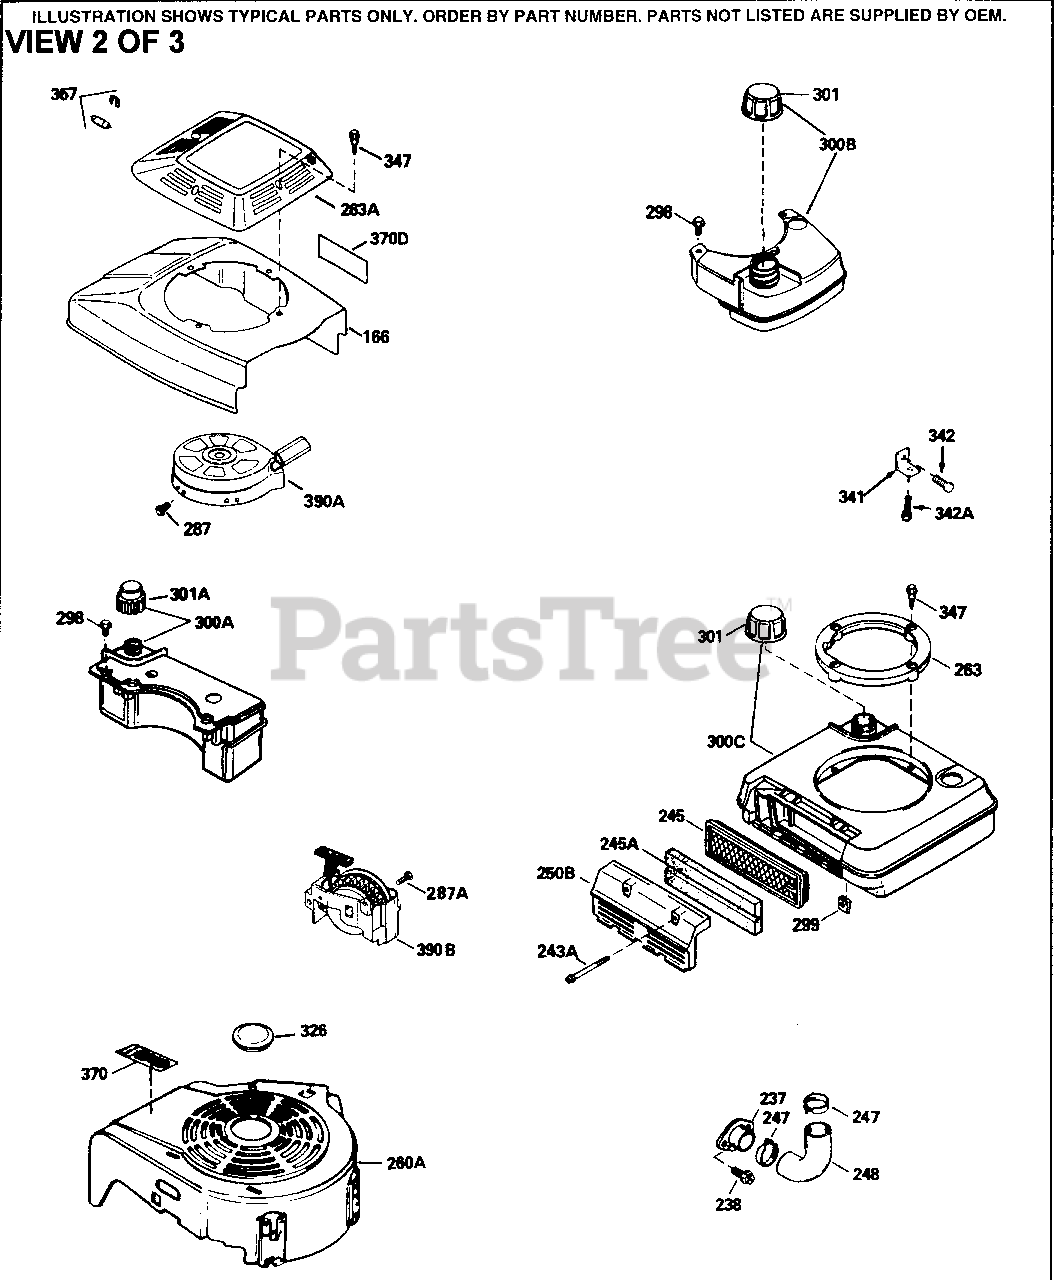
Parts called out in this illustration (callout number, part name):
238	Screw, 10-32 x 49/64"
287	Screw, 8-32 x 1/2"
301	Fuel Cap (Red)
302	Fuel Cap Retainer
305	Oil Fill Tube
354	Staple
357	Starter Rope Retainer
358	Rope Guide Bracket Ass'y.
999	Summer Maintenance Kit (incl. Oil, Sp ark Plug, Air Cleaners (2), & Ultra-F resh)
